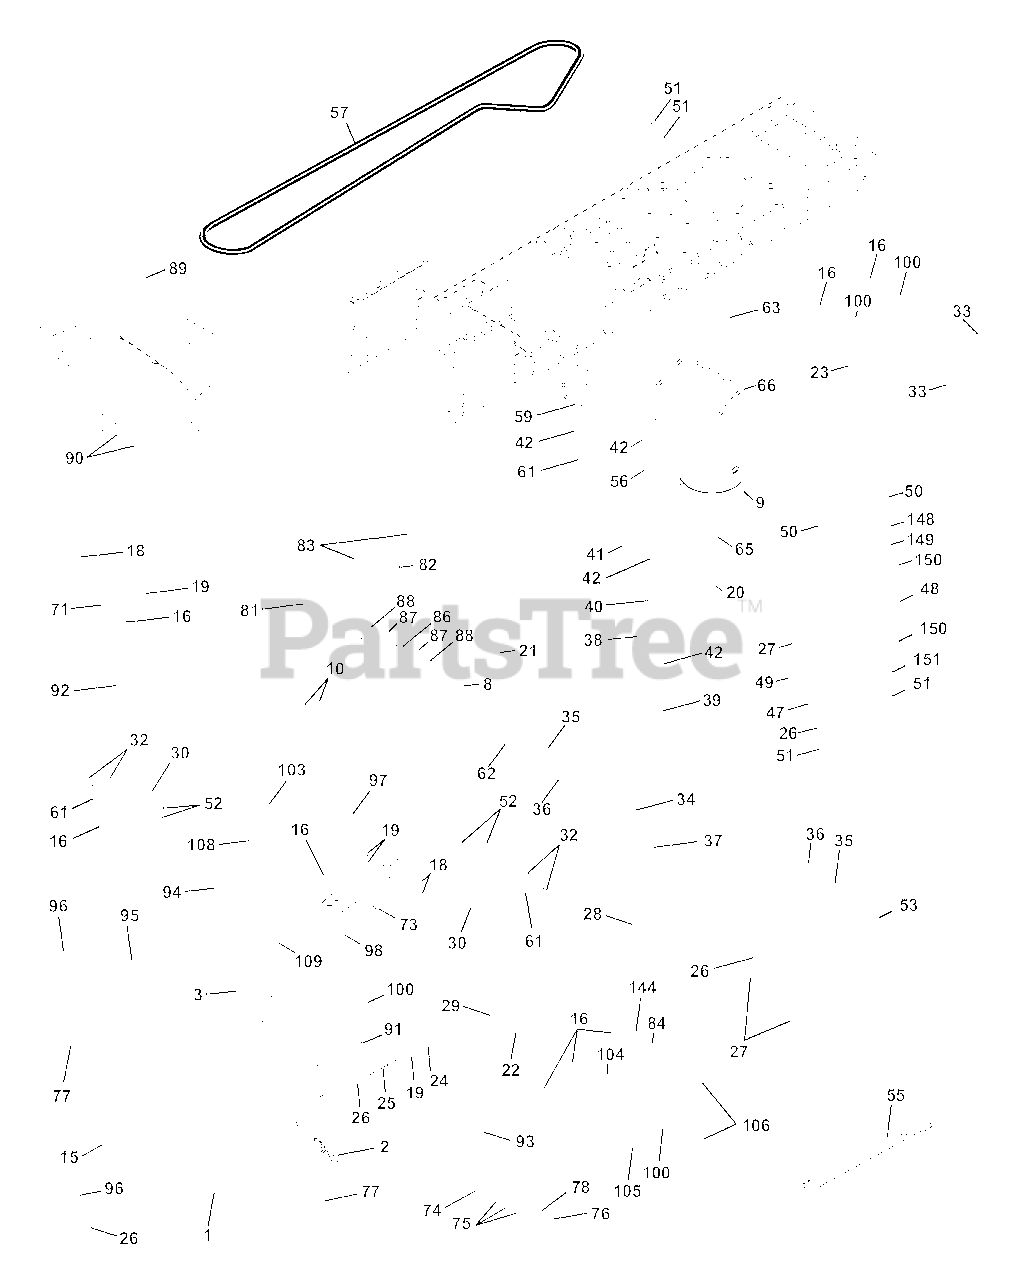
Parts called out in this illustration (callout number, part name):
1	Transaxle
2	Spring, Return, Brake
3	Pulley, Transaxle
8	Rod Shift Fender STLT
9	Clutch, Elect. EVX LT Mag 5217-2
10	Pin Cotter 1/8 x 1 CAD
15	Bolt, Hex Flghd 5/16-18 Gr. 5
16	Nut Lock Hex W/Ins. 5/16-18 Unc P
18	Bolt Fin Hex 3/8-16 Unc x 1 Gr. 5
19	Nut Lock Hex W/Wsh 3/8-16 Unc
20	Bolt Hex 7/16-20 x 4-1/4 Ga. 1.38
21	Knob, Duckhead 1/2-13
22	Rod, Brake Hydro
23	Bracket, Asm Clutch Mtg EVX
24	Nut
25	Spring, Brake Rod
26	Washer
27	Pin Cotter 1/8 x 3/4 CAD.
28	Rod, Parking Brake
29	Cap, Parking Brake
30	Bracket, Transaxle
32	Bolt Hex Hd 5/16-18 Unc x 3/4
33	Bolt Rdhd Sqnk 5/16-18 UNC x 3/4
34	Shaft, Foot Pedal
35	Bearing, Nylon
37	Pin, Roll
38	Pulley, Idler, Flat
40	Spacer, Split
41	Keeper, Belt Idler
42	Washer 13/32 x 13/16 x 12 Gauge
47	Pulley, Idler, V-Groove
48	Bellcrank Assy.
49	Retainer, Belt
50	Bolt
52	Nut Crownlock 5/16-18
53	Link, Clutch
55	Spring, Return, Clutch
56	Bolt Fin Hex 3/8-16 UNC x 1-1/4
57	V-Belt, Ground Drive
59	Keeper, Center Span
61	Screw Thdrol. 3/8-16 x 3/4 Ty. TT
62	Cover, Pedal
63	Pulley, Clutch Electric EVX
65	Washer
66	Keeper Belt Engine Hydro
71	Strap Torque Lh Hydro
73	Strap Torque Rh Hydro
74	Spacer, Split
75	Washer 25/32 x 1-1/4 x 16 Gauge
77	Key, Square
78	Washer 25/32 x 1-5/8 x 16 Gauge
81	Shaft Asm. Cross Hydro
82	Spring Torsion T/A
83	Washer 17/32 x 3/4 x 16 Ga.
84	Rod, Tie Hydro
86	Bushing Rod Steering 629/632 ID
87	Washer 21/32 x 1-1/4 x 16 Ga.
88	Ring Klip #5304-62
89	Console, Shift
90	Nut, Self-Thd Wsh-hd 1/4 Zinc
93	Line Fuel Hydro 4"
94	Fan, Hydro 7"
95	Control Asm Bypass Hydro
96	Retainer Spring 1" Zinc/Cad
97	Keeper Belt Rh Hydro
98	Nut Keps Hex 3/8-16 Unc
100	Washer 11/32 x 3/4 x 16 Ga.
103	Nut Nylon Insert 1/2-20 Unf.
104	Arm, Control Hydro
105	Screw Cap Hex 5/16 x 18 x 1
106	Bolt Fin Hex 5/16-18 Unc x 1-1/4
108	Screw Hex Wh Hd #10-24 x
109	Adaptor Fan Hydro LT Hyd Alum
146	Bolt Hex Flghd 5/16-18 x 2-1//4
147	Bolt Hex Flghd 5/16-18 x 1-1/2
149	Spacer Retainer PM Mower
150	Bushing Nylon Collered
151	Washer 13/32 x 2 x 10 Ga.
